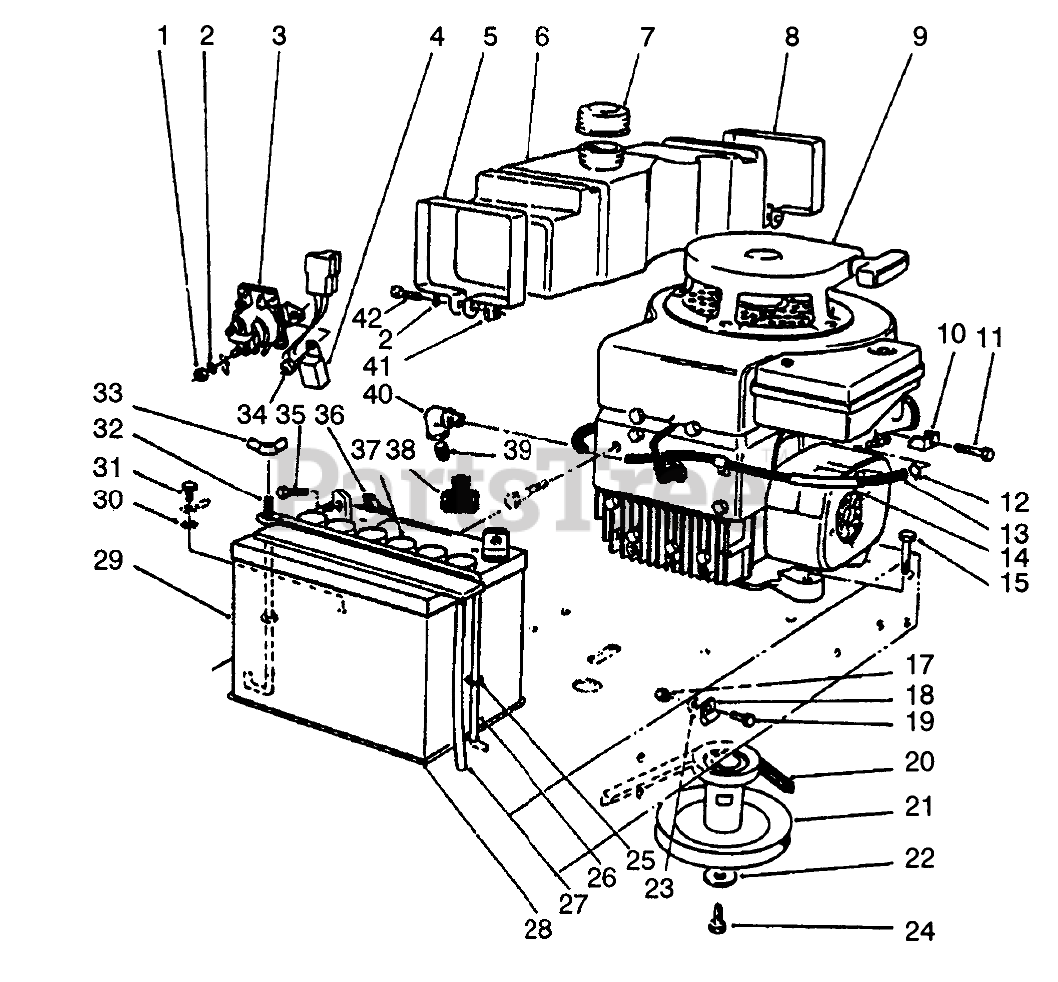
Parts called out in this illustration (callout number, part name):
1	NUT-JAM
2	WASHER-LOCK
3	SOLENOID
4	Module Interlock
5	Retainer-Front
6	TANK-5 QT GAS
7	GAS CAP ASM
8	Retainer-Rear
9	Engine-10 H.P. B & S
10	CLAMP-CASING
11	SCREW W ENGINE
12	CLAMP-HOSE
13	HOSE -RETURN
14	SUPPORT-FUEL LINE
15	SCREW-HH
17	NUT-LOCK, NI
18	CLAMP
19	SCREW-HH
20	V-BELT, TRACTION
21	ENGINE PULLEY ASM
22	WASHER-FLAT
23	WASHER-PLAIN
24	SCREW-HH
25	O-RING
26	HOLDDOWN-BATTERY
27	TUBE-BATT DRAIN/80-2600
28	PAD-SKID, ANTI
29	Battery
30	WASHER-LOCK, INTERNAL
31	SCREW-HWHTF
32	POST-BATTERY
33	NUT-WING
34	NUT-LOCK, NI
35	SCREW-HH
36	NUT-WING
37	CAP-BATTERY
38	BOOT-TERMINAL
39	3/8 PIPE PLUG
40	ELBOW-STREET, 90 DEG
41	NUT-SQUARE
42	SCREW-HSH
